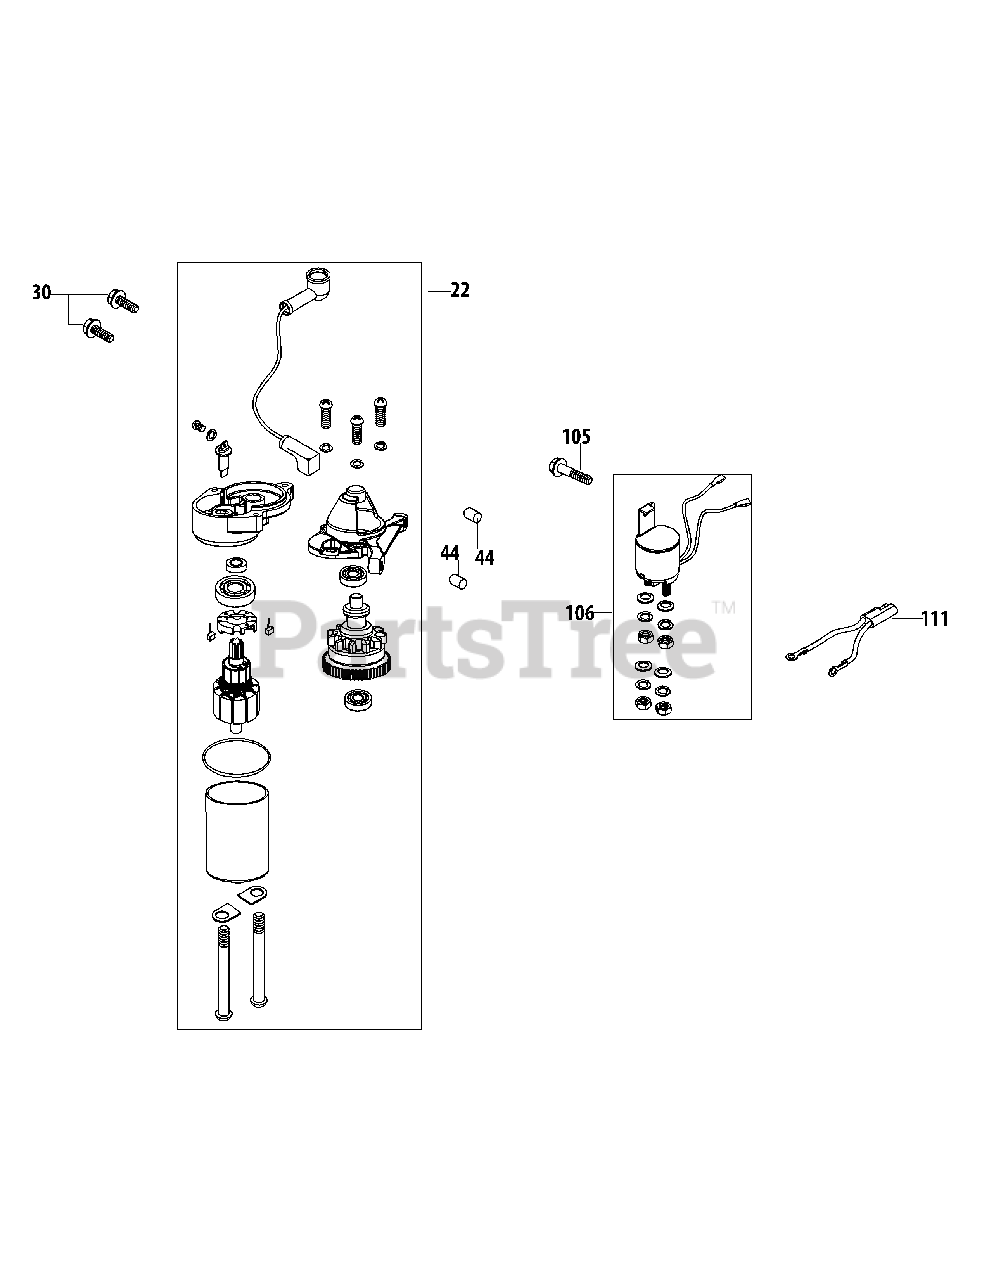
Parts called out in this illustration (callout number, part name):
22	Electric Starter Assembly (53:9)
30	Bolt M6X30
44	Starter Housing Dowel 8X8
105	Bolt M6X35
106	Starter Relay Assembly
111	Power Connector Harness
